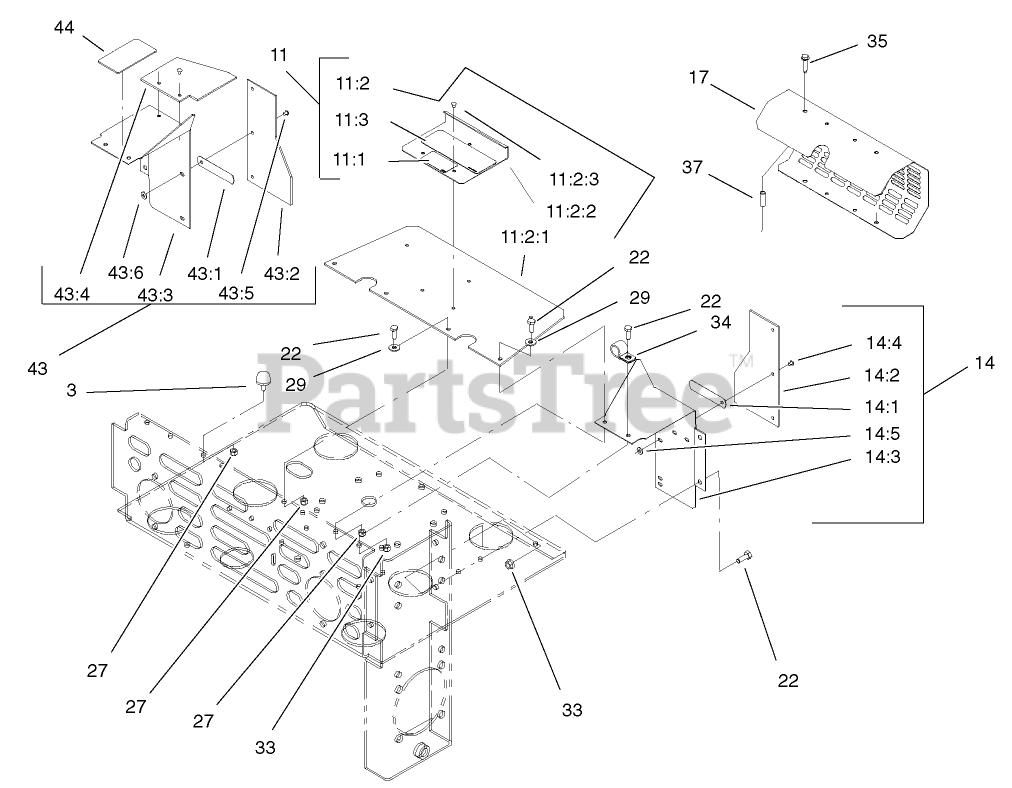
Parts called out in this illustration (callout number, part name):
3	BUMPER
11	SHIELD ASM
11:1	DECAL-IMPORTANT
11:2	SHIELD AND LIFT ASM
11:2:1	SHIELD-ENGINE
11:2:2	LIFT-SHIELD
11:2:3	RIVET-POP
11:3	DECAL-DEVICES, ROTATING
14	LH SHIELD ASM
14:1	CLIP-BAFFLE, REAR
14:2	SHIELD-ENGINE
14:3	BAFFLE-ENGINE SHIELD, LH
14:4	RIVET-POP
14:5	WASHER-FLAT
17	GUARD-MUFFLER
22	SCREW-HH
27	NUT-LOCK, NI
29	WASHER-FLAT
33	NUT-HF
34	CLIP-LOOM
36	WASHER-SPRING
37	SPACER
43	RH SHIELD ASM
43:1	CLIP-BAFFLE, REAR
43:2	SHIELD-ENGINE
43:3	SHIELD-RH
43:4	BAFFLE-COOLER, ENGINE
43:5	RIVET-POP
43:6	WASHER-FLAT
44	DECAL-ROUTING, BELT
